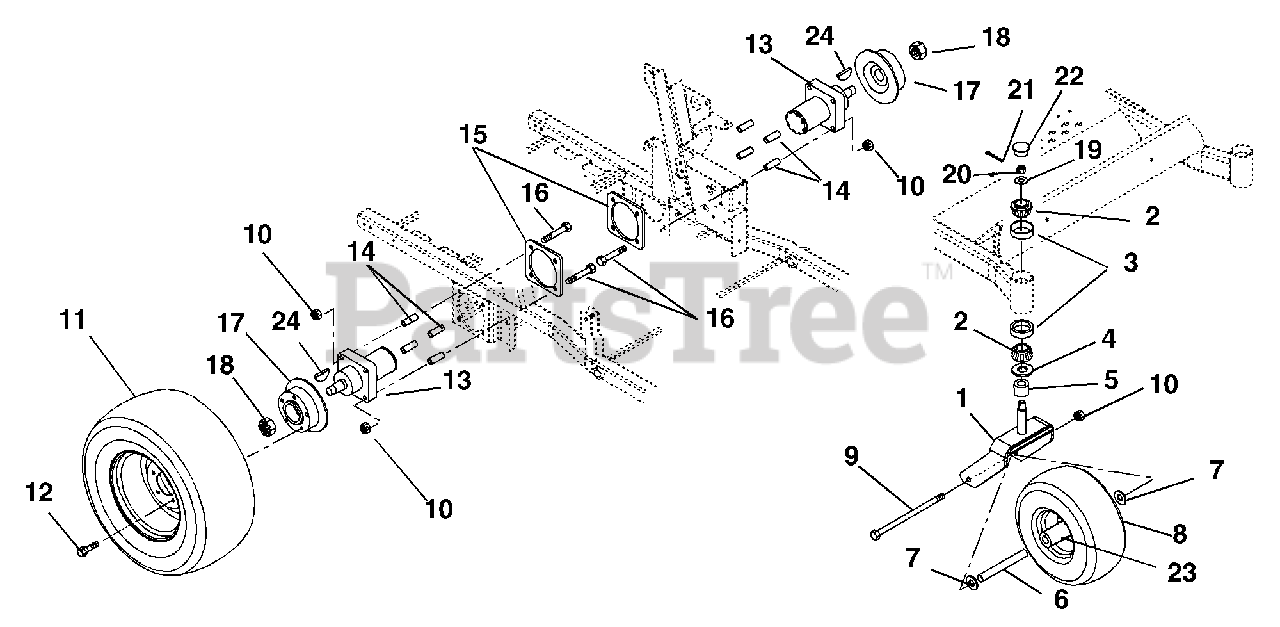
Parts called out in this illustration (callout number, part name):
1	Fork
2	Bearing-Cone w/ Grease
3	Bearing-Cup 1.980 x .420
4	Bearing Seal 1.5 x 2 x .18
5	Spacer, PM, 1.03 I.D. x 1.5 O.D. x .375
6	Spacer-Wheel
7	Washer-Flat-Steel .515 x 1.625 x .250
8	Wheel/Tire Assembly
8	Tire, 15 x 6-6
9	Bolt-Hex .50-13 x 9.00 Grade 5
10	Nut-Locking-Top-Flange .50-13
11	Wheel-Tire 23 x 10.50 - 12 Multi-Trac (043, 044, 311)
11	Wheel-Tire Assembly 23 x 9 50-12 (042, 310)
11	Wheel-Tire Assembly, 23X10.50-12 (051)
11	Tire 23 x 10.50 (043, 044, 051)
11	Tire, 23 x 9.50-12 Multitrac (042, 310)
12	Bolt-Lug Grade 8; .50-20 Unf x .75 Long 60 Degree
13	Hydraulic Wheel Motor
14	Bushing-Sleeve .513 x .748 x 2.13
15	Plate, Motor Support
16	Bolt-Hex .50-13 x 5.00 Grade 5
17	Hub and Disc
18	Nut -Lock Jam Patch
19	Washer-Flat-Steel .755 x 1.375 x .062
20	Nut-Slotted .75-16
21	Pin-Cotter .16 x 1.00
22	Cap-Dust
23	Bearing, 25MM I.D. x 52MM OD x 15MM
24	Key-Woodruff .31 x 1.00
